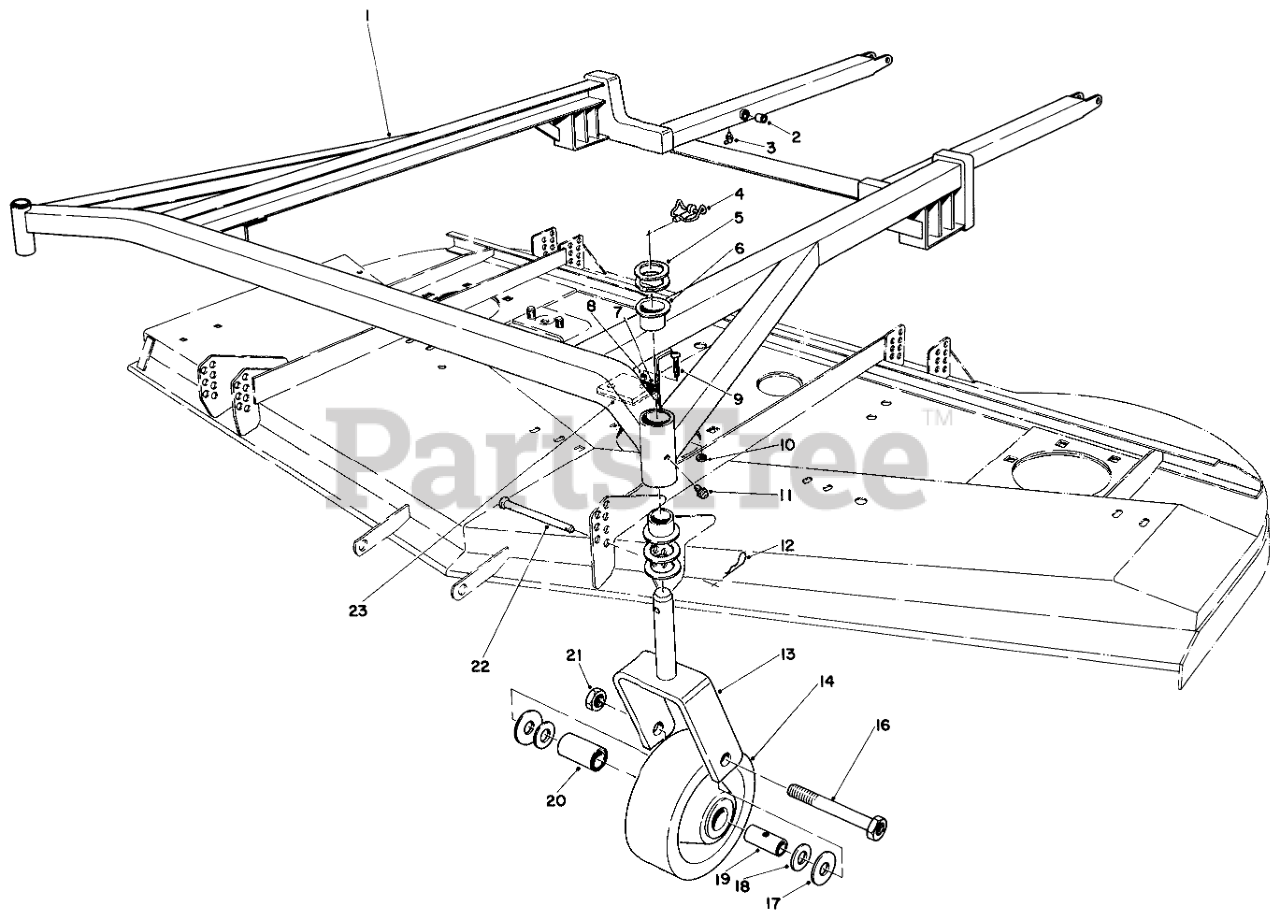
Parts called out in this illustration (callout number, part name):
1	Frame (Incl. Ref. #2, 3 & 6)
2	7/8 ID X 1.128 X 7/8 LG BSHG
3	FITTING-GREASE, 90 DEG
4	PIN-LYNCH
5	WASHER-THRUST
6	Bushing
7	CUSHION-RUBBER
8	SPACER
10	NUT-LOCK, NI
11	FITTING-GREASE
12	PIN-HAIR
13	FORK-Castor
14	Castor Wheel (Incl. Ref. #17-20)
16	AXLE ASM
17	THRUST WASHER
18	BEARING RETAINER
19	BUSHING
20	ROLLER BEARING
21	NUT-HEX
22	PIN-CLEVIS
23	SHIM-CUSHION
